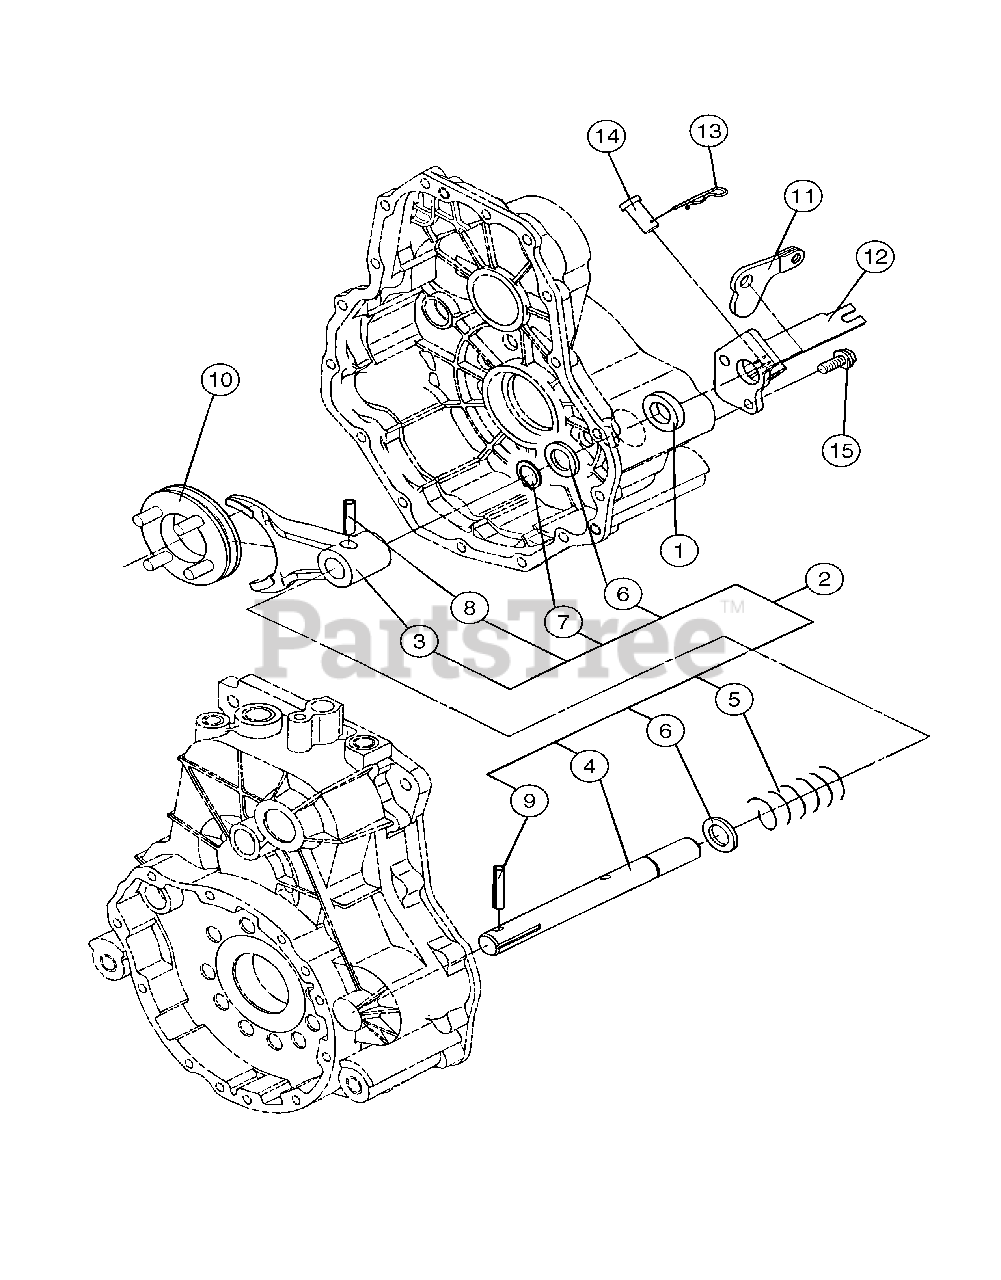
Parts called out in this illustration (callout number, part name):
1	Seal, TC4 20 35 7
2	Differential Lock Kit
3	Fork, Differential Lock
4	Shaft, Differential Lock
5	Spring, Differential Lock
6	Spacer, 20 x 32 x 3.2
8	Pin, 8.0A x 32
9	Pin, 8.0A x 40
10	Slider, Differential Lock
11	Arm, Differential Lock
12	Bracket, Differential Lock
13	Pin, 12
15	Tapping Screw, 8 x 20
15	Flange Bolt, M8 x 20
